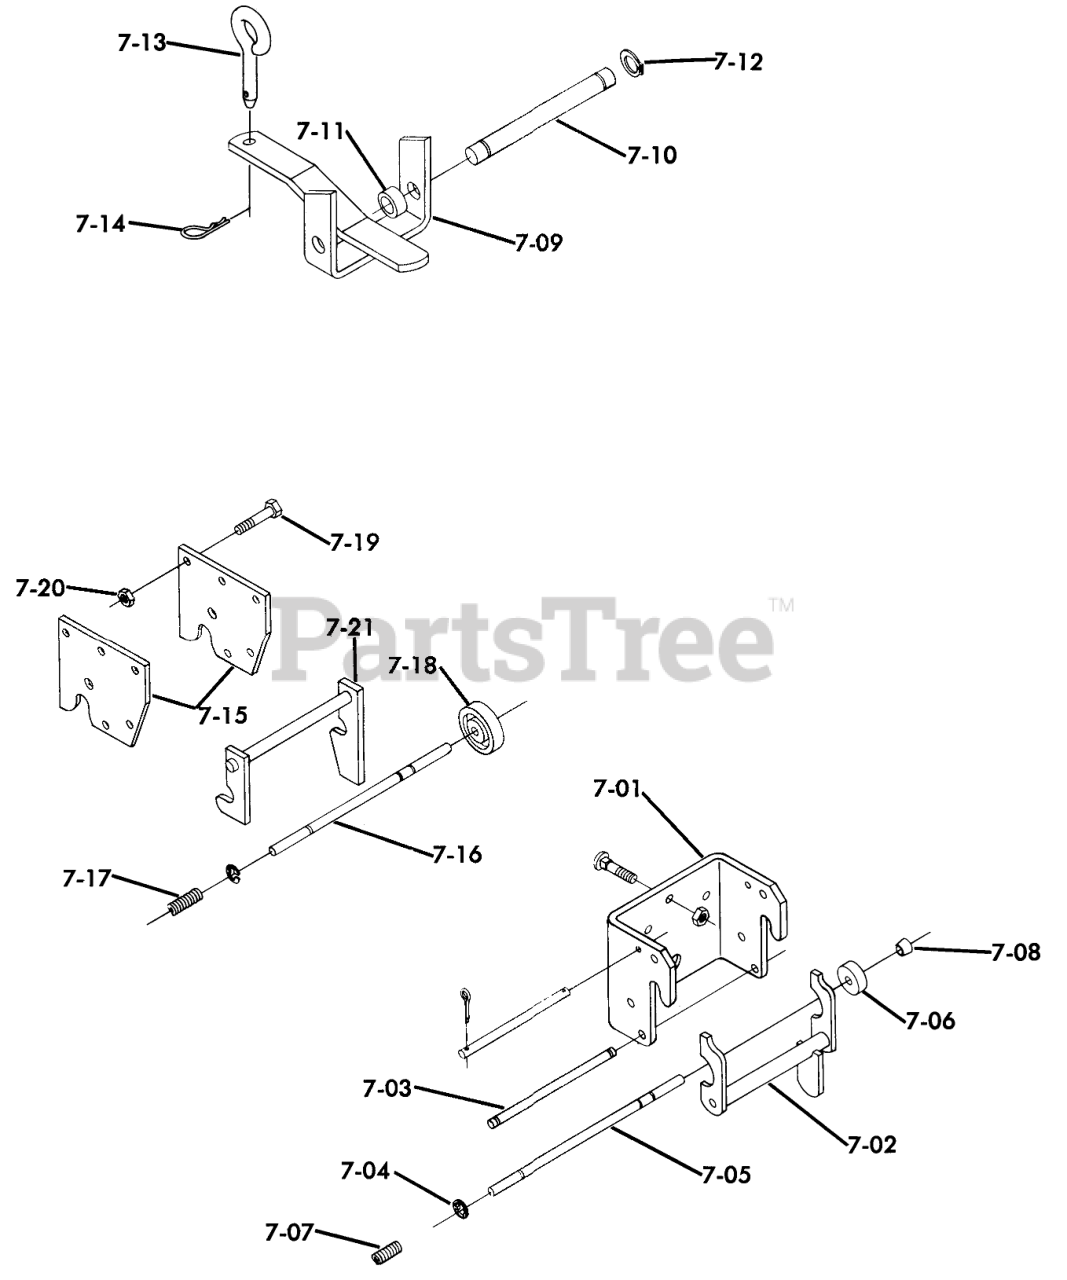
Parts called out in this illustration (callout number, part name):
7-01	Front Hitch
7-02	Assy-Latch
7-03	ROD-LATCH PIVOT
7-04	Lock Rod
7-05	ROD-LOCK
7-07	SPRING
7-08	CAP-ROD, PLUNGER
7-09	Hitch
7-10	PIN-STATIONARY HITCH
7-11	Spacer
7-12	E-RING
7-13	Pin-Tool
7-14	Hairpin Cotter
7-15	Hitch Plate
7-17	ASSY MID HITCH LA R
7-19	BOLT
7-20	Nut
7-21	ASSY MID HITCH LA R
